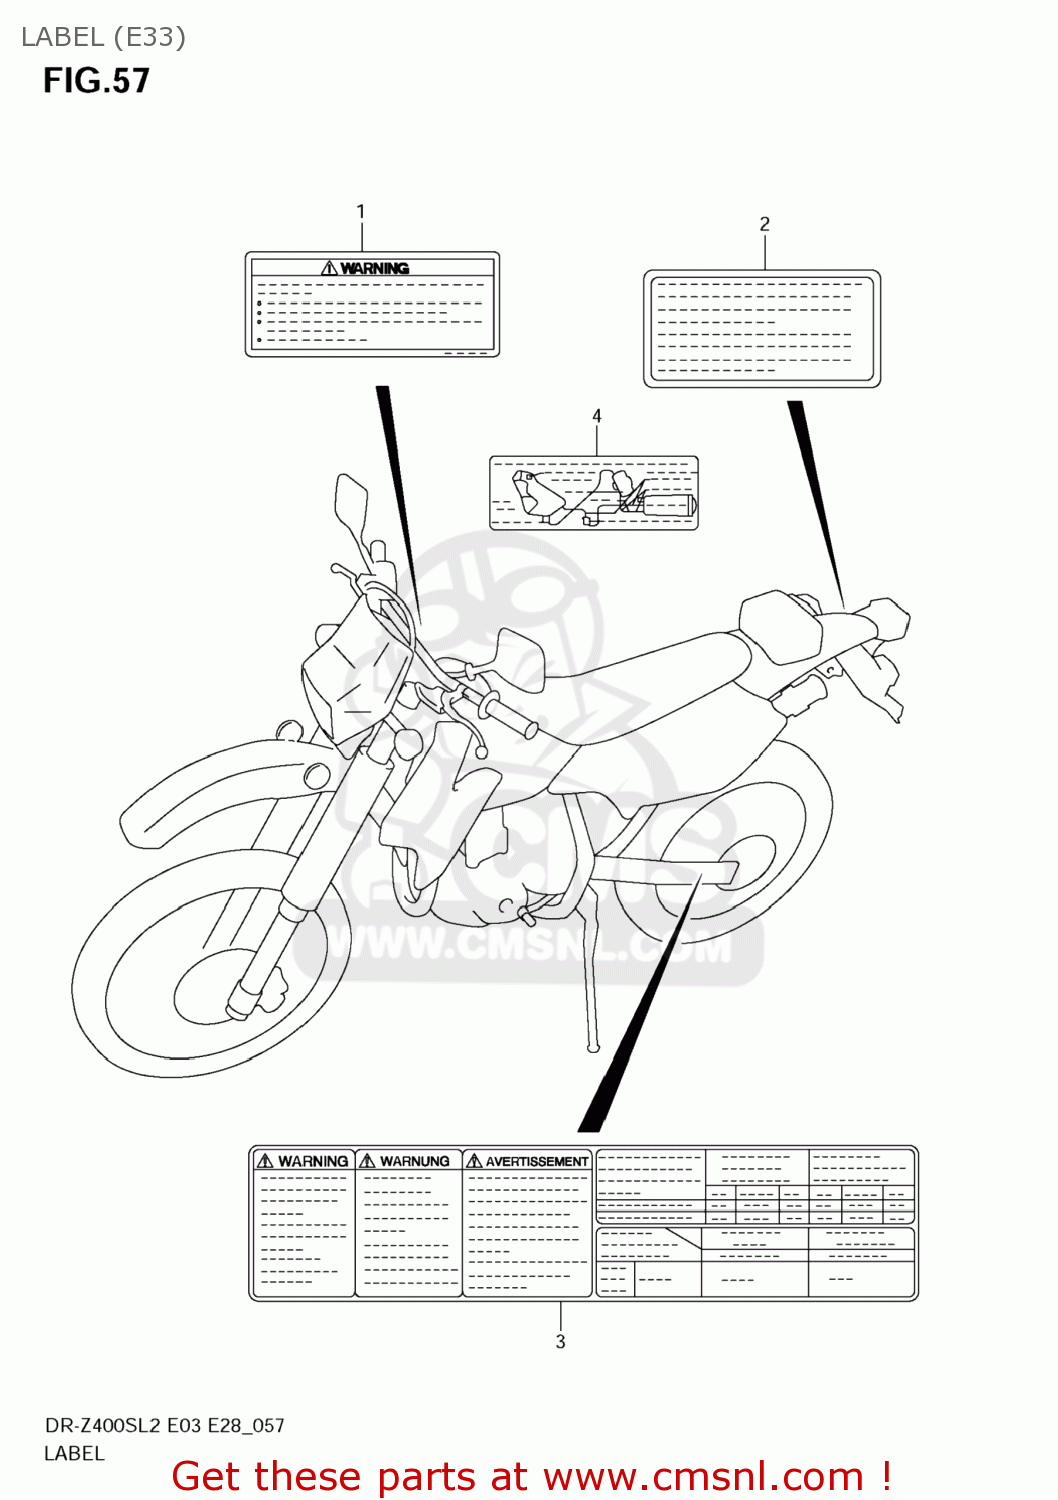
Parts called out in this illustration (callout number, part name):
1	LABEL,GENERAL WARNING
2	LABEL,MANUAL NOTICE
3	LABEL,TIRE INFORMATION
4	LABEL,VACUUM HOSE ROUTING
5	MANUAL,OWNER'S
